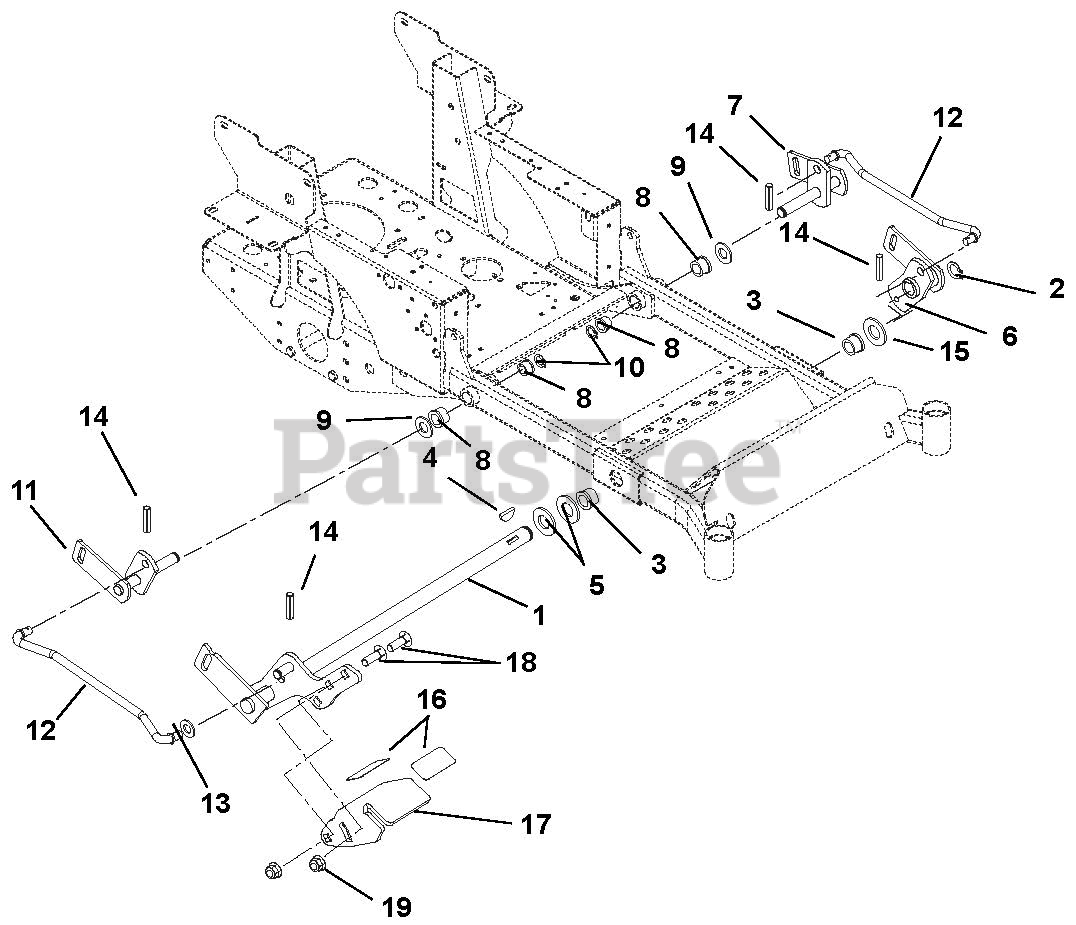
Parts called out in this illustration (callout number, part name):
1	Weldment, Mechanical Deck Lift
2	Ring, Retaining External 1.00 x .078
3	Bushing, Flange Nylon 1.020 x 1.385 x .75 x 1.75
4	Key, Woodruff .25 x 1.00
5	Washer, Flat Steel 1.062 x 2.0 x .134
6	Weldment, Left Hand Mower Lift Arm
7	Weldment, Left Hand Rear Mower Lift Arm
8	Bushing, Flange Nylon .762 x 1.0 x .580 x 1.48
9	Washer, Hardened Steel .758 x 1.23 x .031
10	Ring, Retaining External .689 x .077
11	Weldment, Right Hand Rear Mower Lift Arm
12	Rod, Lift Assist
13	Washer, Flat Steel .630 x 1.25 x .062
14	Pin, Roll .25 x 1.25 Stainless Steel
15	Washer, Hardened Thrust 1.00 x 1.55 x .03
16	Grip, Pedal
17	Foot Pedal, Adjustable Black
18	Bolt, Round Hd. Square Neck .50-13 x 1.50 Grade 5 YZ
19	Nut, Locking Top Flange .50-13
